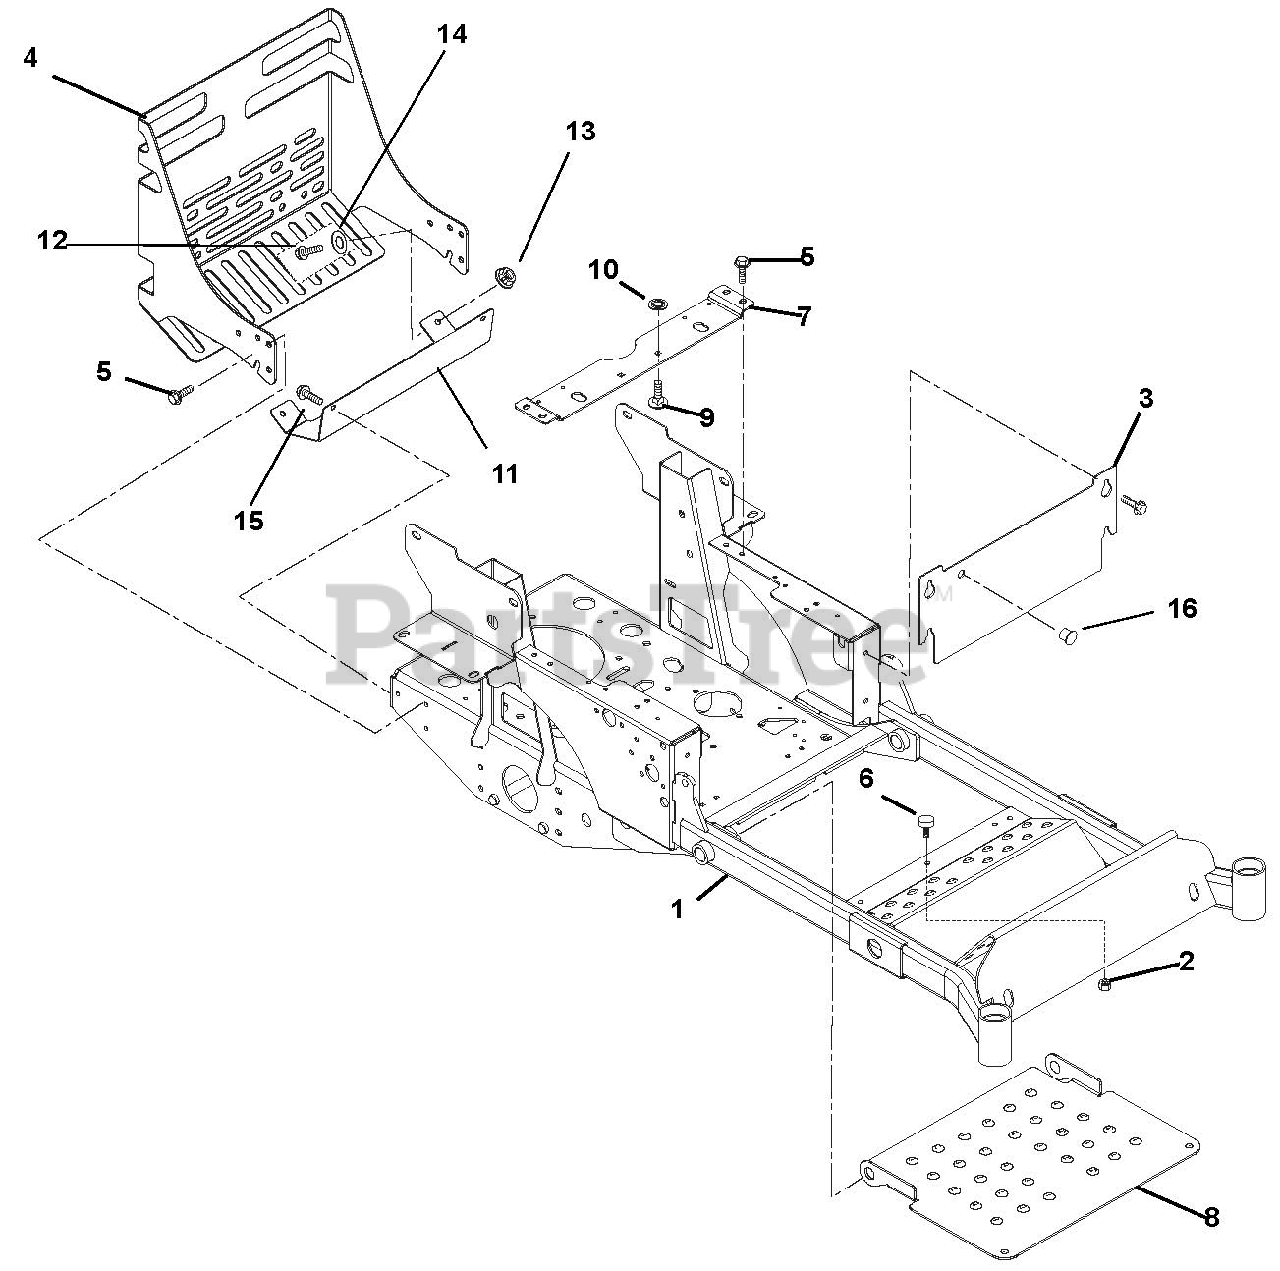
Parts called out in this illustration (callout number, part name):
1	Frame, Compact-Z
2	Nut, Spin Lock Flange .312-18
3	Access Panel
4	Bumper, Rear
5	Screw, Tapping .38-16 x .75 Hex Washer Head
6	Bumper, Rubber
7	Seat Support
8	Panel, Inspection
9	Bolt, Round Head Square Short Neck .31-18 x .75 Grade 5
10	Nut, Push .312
11	Heat Shield, Compact Z
12	Bolt, Hex .38-16 x .75 Grade 5
13	Nut, Nyloc Flange .38-16
14	Washer, Flat Steel .438 x 1.00 x .083
15	Screw, Tapping .38-16 x .50 Hex Washer Head
16	Plug, Hole .56
